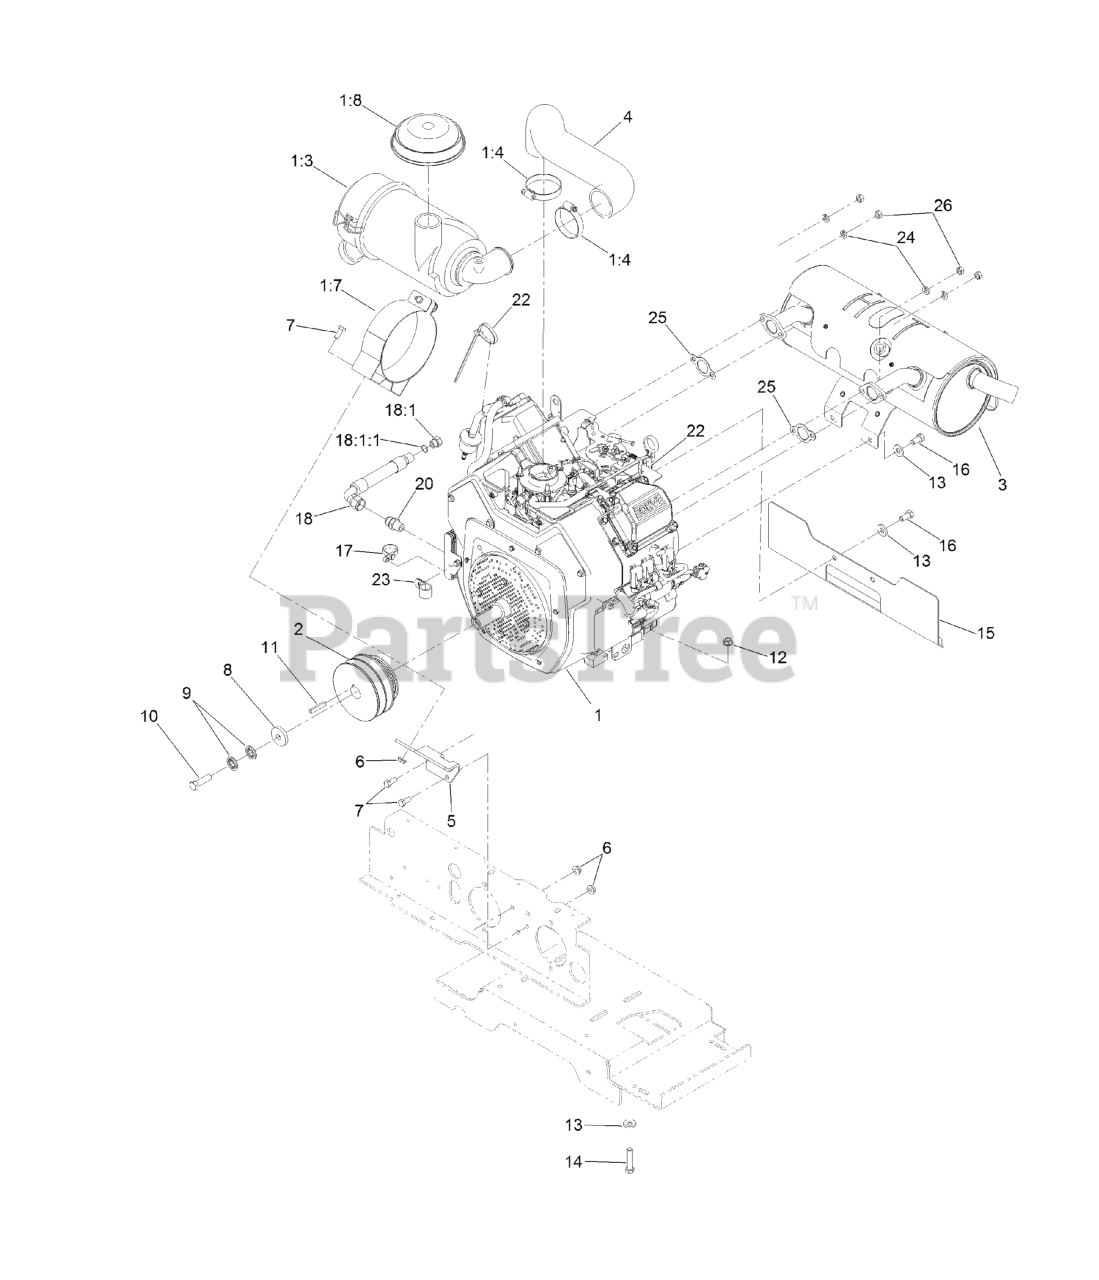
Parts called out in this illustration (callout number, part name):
1:3	AIR CLEANER CANISTER ASM
1:4	CLAMP-HOSE
1:7	BRACKET-FILTER, AIR
1:8	HOOD-CLEANER, 2" AIR INTA
4	HOSE-AIR INTAKE
5	BRACKET-FILTER, AIR
7	SCREW-HH
8	WASHER-CLUTCH
9	WASHER-SPRING
10	SCREW-HH
11	KEY-SQUARE
12	NUT-HHF, WHIZ
13	WASHER-BELLEVILLE
14	SCREW-HH
15	SHIELD-EXHAUST
16	SCREW-HH
17	Tie, Cable
18	OIL DRAIN HOSE ASM
18:1	PLUG-HH
18:1:1	O-RING
20	FITTING-STRAIGHT
22	TIE-PLASTIC
23	CLIP-LOOM
24	WASHER-LOCK
25	GASKET (KOHLER)
26	NUT-HEX
